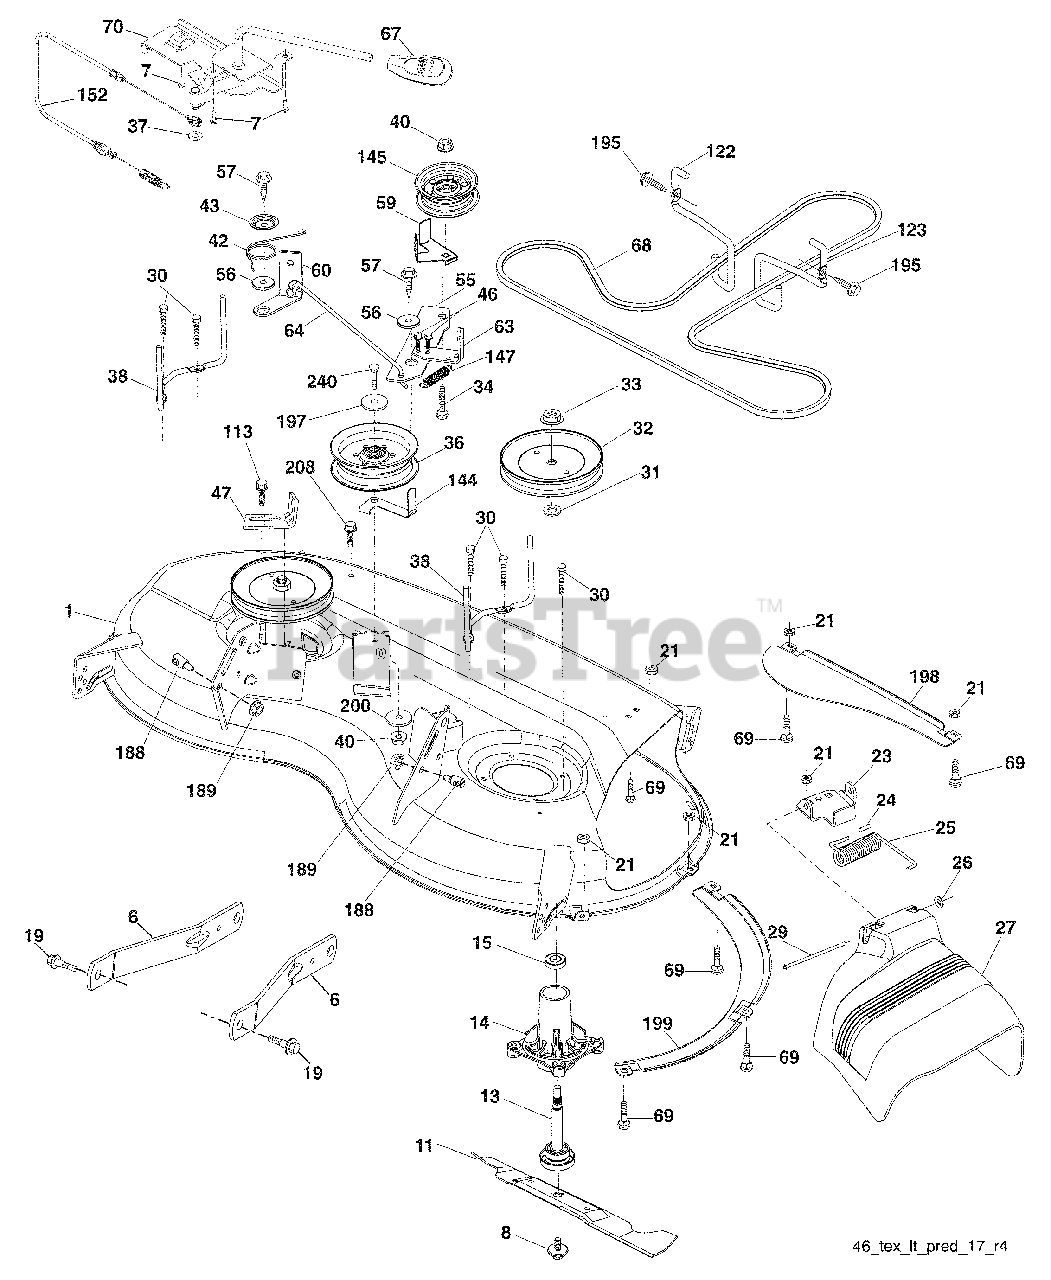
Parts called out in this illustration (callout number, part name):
1	Mower Housing
2	Cover Mandrel RH
3	Cover Mandrel LH
6	Arm Suspension
7	Screw #10 x 0.750
8	Bolt/Washer Asm 7/16-20 unf
11	Blade Mower
13	Shaft Assembly, Mandrel
14	Housing, Mandrel
15	Bearing, Ball, Mandrel
19	Bolt, Shoulder
21	Nut
23	Bracket, Deflector
24	Cap, Sleeve
25	Spring, Torsion, Deflector
27	Shield, Deflector
29	Rod, Hinge
30	Screw Thdrol Rolling Wsh Hd
31	Washer, Spacer
32	Pulley, Mandrel
33	Nut, Toplock, Flanged
34	Bolt Carr Sh. 3/8-16 x 1-1/2 Gr. 5
36	Pulley, Idler, Flat
37	Washer 13/32 x 13/16 x 16 Ga.
38	Keeper Belt LH Mandrel
40	Nut, Lock Flg. 3/8-16 unc
42	Spring Brake
43	Spring Brake Retainer
47	Bracket Clutch Cable
55	Arm, Idler
56	Spacer, Retainer
57	Screw Hexwsh Thd 3/8-16 x 1
59	Guard, Tuv Idler (94)
60	Arm Brake Mower LH
62	Bolt 3/8-16 unc x 2-1/4 Gr. 5
63	Arm Brake Mower
64	Linkage Brake
67	Handle, Clutch Cable
68	Belt
69	Bolt
70	Clutch Asm. Cable
113	Screw 5/16-18
116	Bolt, Shoulder
117	Wheel, Gauge
119	Washer 13/32 x 1-1/4 x 12 Ga.
122	Keeper Belt Eng. LH
123	Keeper Belt Eng. RH
144	Keeper Belt
145	Pulley Idler
147	Spring Return
152	Cable Clutch Manual w/Spr.
188	Stud Fastener
189	Nut Lock Hex Flange
195	Screw 3/8-16 x 3/4
197	Washer 13/32 x 13/16 x 12 Ga.
198	Baffle Center Front
199	Baffle Front RH
200	Washer 13/32 x 1 x 1/2 11 Ga.
208	Screw 3/8-16 x 1/2
